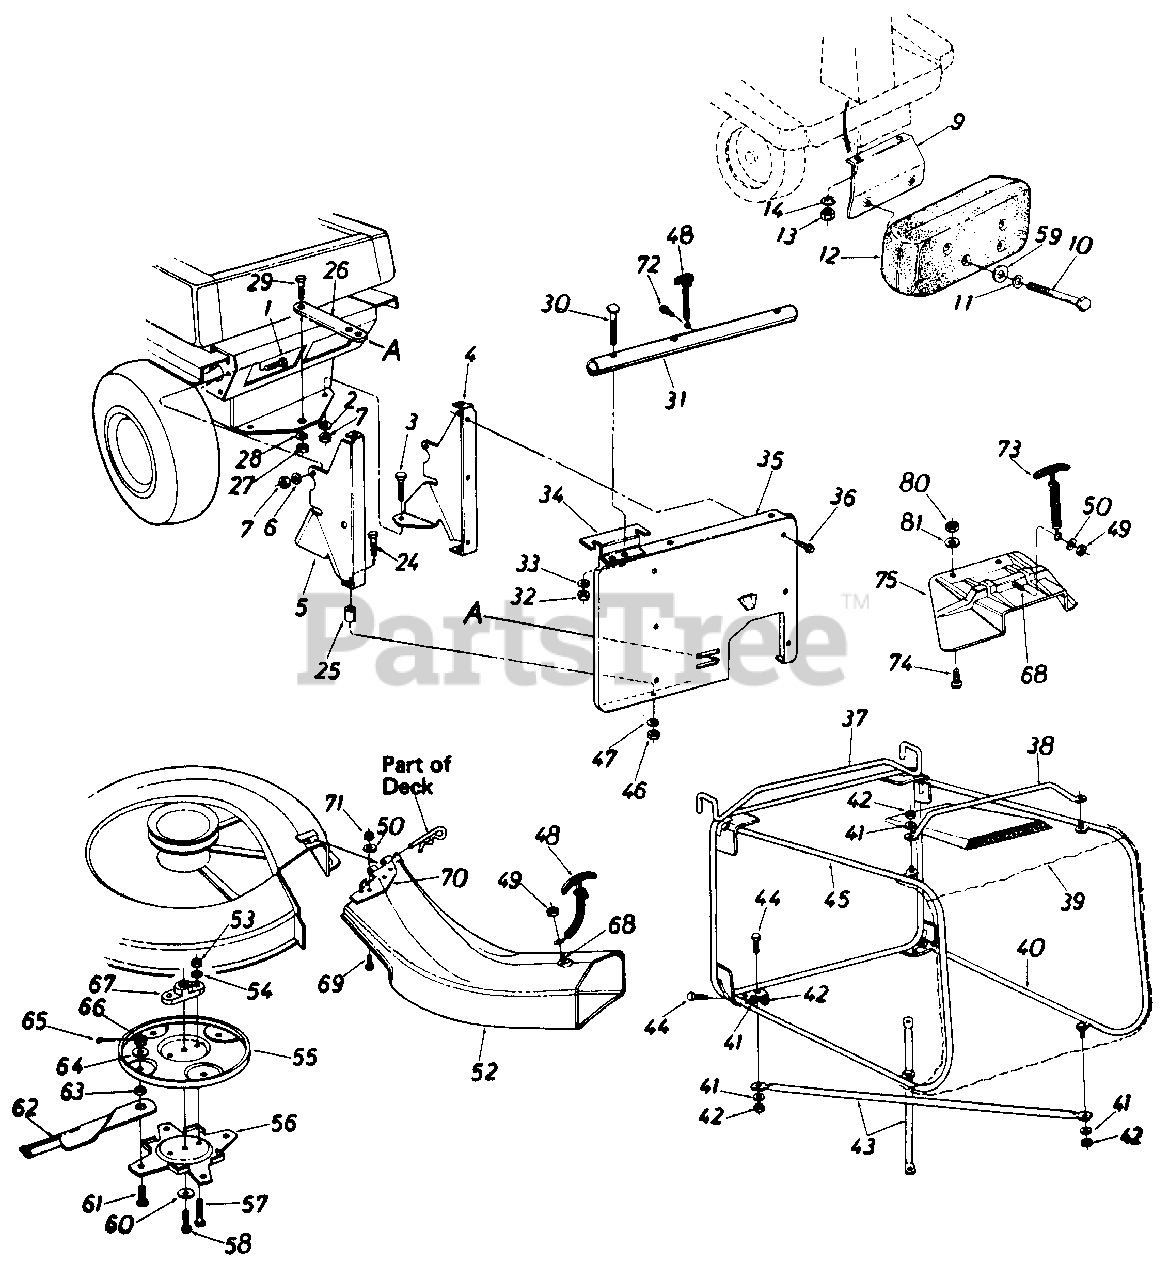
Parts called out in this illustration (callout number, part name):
1	Hex Bolt 5/16-18 x 1.0" Lg.
2	L.-Wash. 5/16" I.D.
3	Hex Bolt 5/16-18 x 1.0" Lg.
4	Catcher Support Brkt-R.H.
5	Catcher Support Brkt-L.H.
6	L.-Wash. 5/16" I.D.
7	Hex Nut 5/16-18 Thd.
9	Counterweight Support Brkt. Ass'y.
10	Hex Bolt 3/8-16 x 4.5" Lg.
11	Belleville Wash. .40" I.D. x .88" 0. D.
12	Counterweight 38 lbs.
13	Hex Nut5/16-18 Thd.
14	L.-Wash. 5/16" I.D.
24	Hex Bolt 5/16-18 x 1.50" Lg.
25	Spacer .380" I.D. x .47" O.D. x 1.0" Lg.
28	L.-Wash. 1/2" I.D.
29	Hex Bolt 1/2-20 x 1.0" Lg.
30	Curved Carriage 8O1t 5/16-18 x 1.75" Lg.
33	L.-Wash. 5/16" I.D.
34	Grass Catcher Support Plate
35	Rear Discharge Panel
36	Hex Wash. Hd. Self Tap. Scr. 1/4-20 x .50" Lg.
37	Grass Catcher Frame Ass'y.
42	Hex L.-Nut 1/2-20 Thd
43	Bottom Cross Brace
44	Hex Bolt 1/4-20 x .62" Lg.
47	L-Wash. 5/16" I.D.
48	Hook Latch Ass'y.
49	Hex L. Nut 1/4 20 Thd.
50	Fl.-Wash. 1/4" I.D.
52	R.D. Banana Chute Ass'y.
53	Hex Nut 5/16-24 Thd.'
54	L.-Wash. 5/16" I.D.
55	Upper Blade Disc
58	Hex Bolt 3/8-24 x 1.0" Lg.
59	Fl.-Wash. .39" I.D. x 1.12" O.D.
60	Bell.-Wash. 39" I.D. x 1.38"
61	Shld. Bolt. .50" Dia. x .360 Spec.
62	30" Blade Tip
63	Spacer .505" I.D. x .75" O.D. x 1.25" Lg.
64	Fl.-Wash. .50" I.D. x 1.25" O.D.
65	Cotter Pin 3/32" Dia. x 1.0" Lg.
66	Hex Slotted Nut 1/2-20 Thd.
67	Blade Adapter
68	Hex Bolt 1/4-20 x .50" Lg.
69	Truss Mach. Scr. 1/4-20 x .50" Lg.
72	Hex AB Tap Scr. 1/4 x .62" Lg.
73	Hook Latch Ass'y. 7" Lg.
74	Truss Mach. Scr. 1/4-20 x 50" Lg.
75	R D Chute Extension
80	Hex L.-Nut 1/4-20 Thd.
81	Fl.-Wash. .281" I.D. x .50" O.D. x .063
